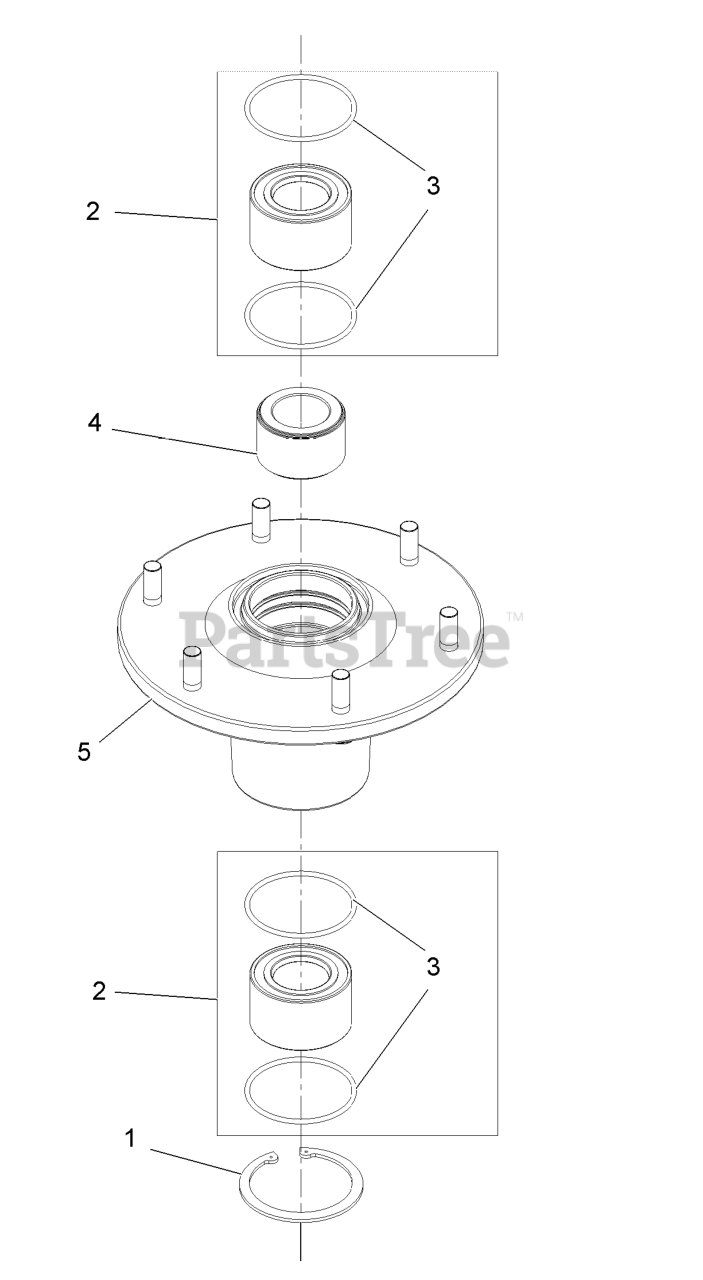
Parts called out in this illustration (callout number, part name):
1	RING-RETAINING
2	ASM, BEARING W/ORINGS
4	SPACER,BEARING
5	ASM,HOUSING W/STUDS
